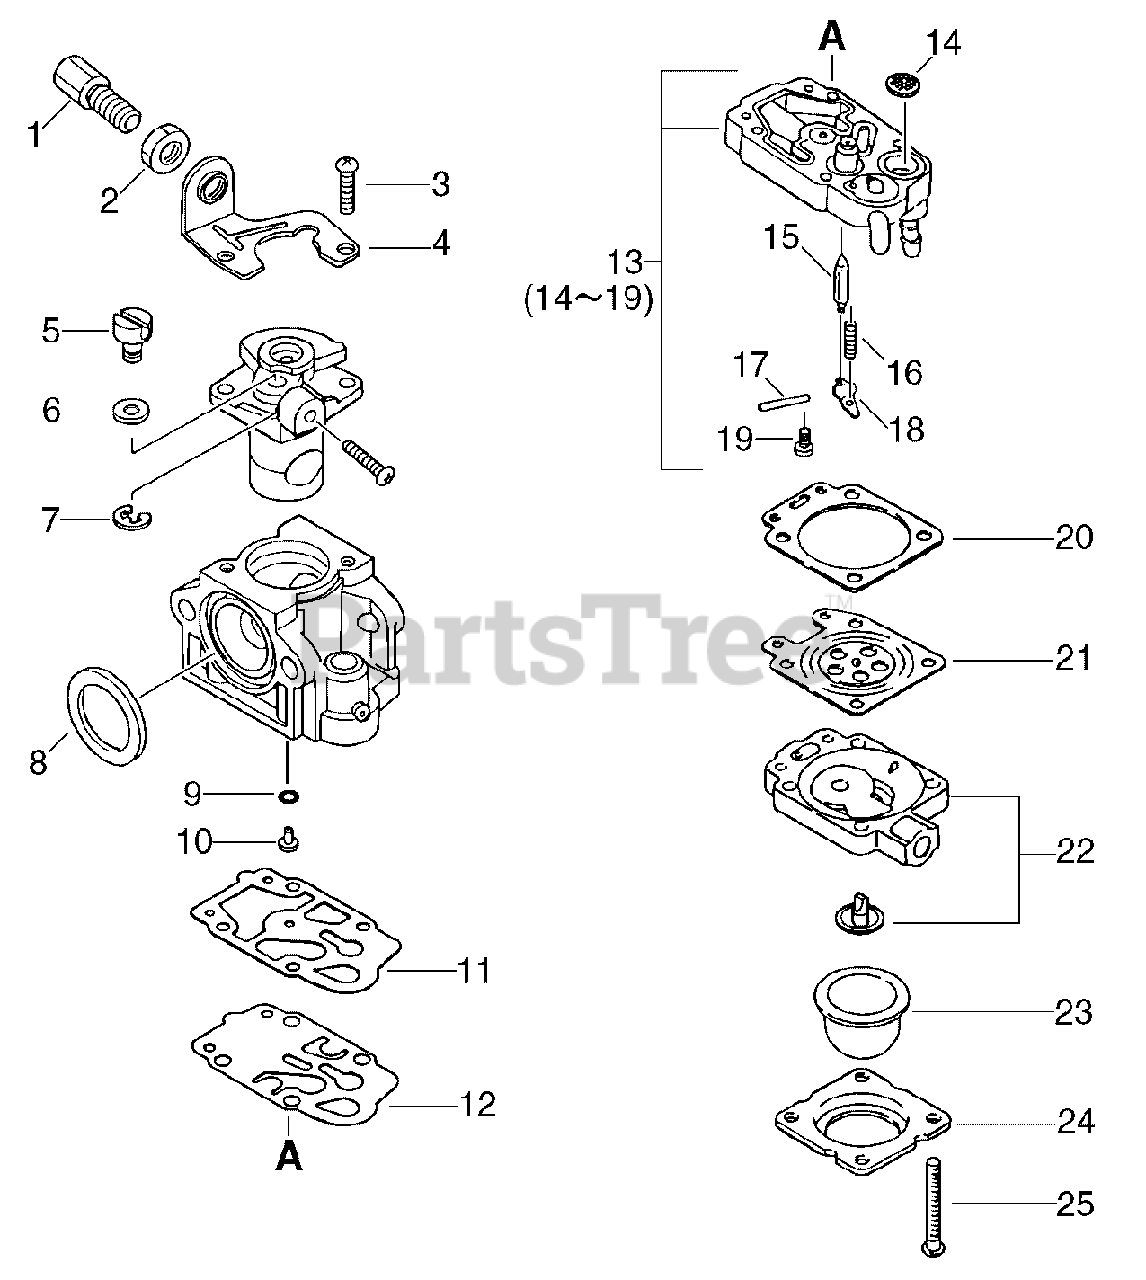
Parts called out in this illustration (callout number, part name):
1	SCREW, ADJUST
4	BRACKET, THROTTLE CABLE
7	RING, RETAINING
9	O-RING
11	GASKET, PUMP
12	DIAPHRAGM, PUMP
13	BASE, PURGE
14	STRAINER
15	VALVE, INLET NEEDLE
16	SPRING, METERING LEVER
17	PIN, METERING LEVER
18	LEVER, METERING
19	SCREW, METERING LEVER PIN
20	GASKET, METERING
21	DIAPHRAGM, METERING
22	PURGE BASE ASSY
23	BULB, PURGE
24	RETAINER, PURGE BULB
25	SCREW, PUMP COVER
